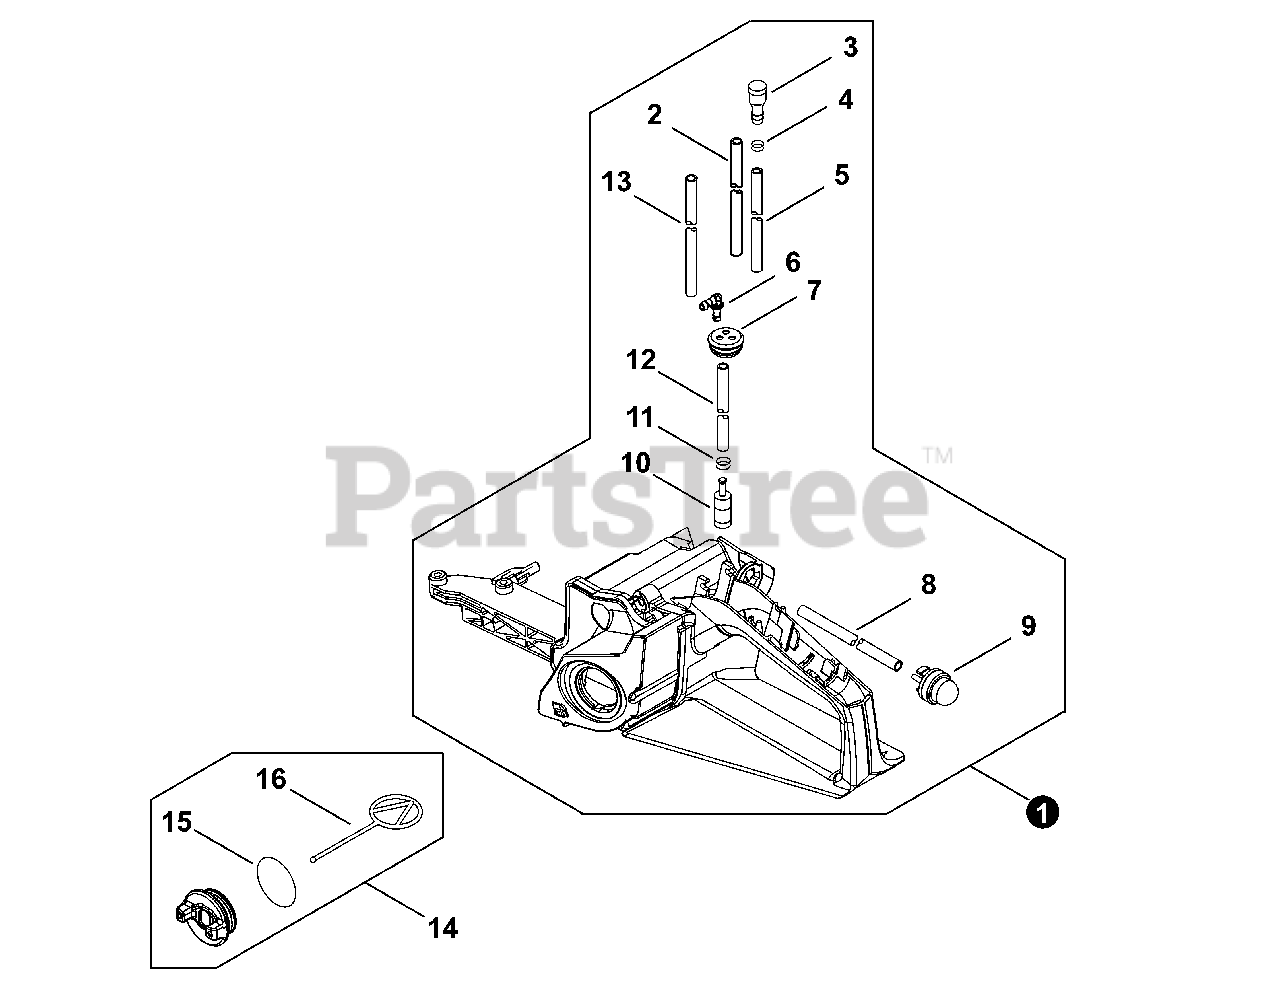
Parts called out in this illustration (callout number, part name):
1	HANDLE ASSY, REAR
2	PIPE, FUEL 2.4×5×75
3	VENT ASSY
4	CLIP Ø6.5 MM
5	PIPE 3×6×49
6	CONNECTOR, PIPE
7	GROMMET, FUEL
8	PIPE 2.4×5×165
9	BULB, PURGE
10	FILTER, FUEL
11	CLIP Ø6
12	PIPE, FUEL RETURN
13	PIPE 3×5×160 EPA-KEP-002
14	CAP ASSY, FUEL
15	O-RING 29
16	CONNECTOR, CAP L= 60 MM
